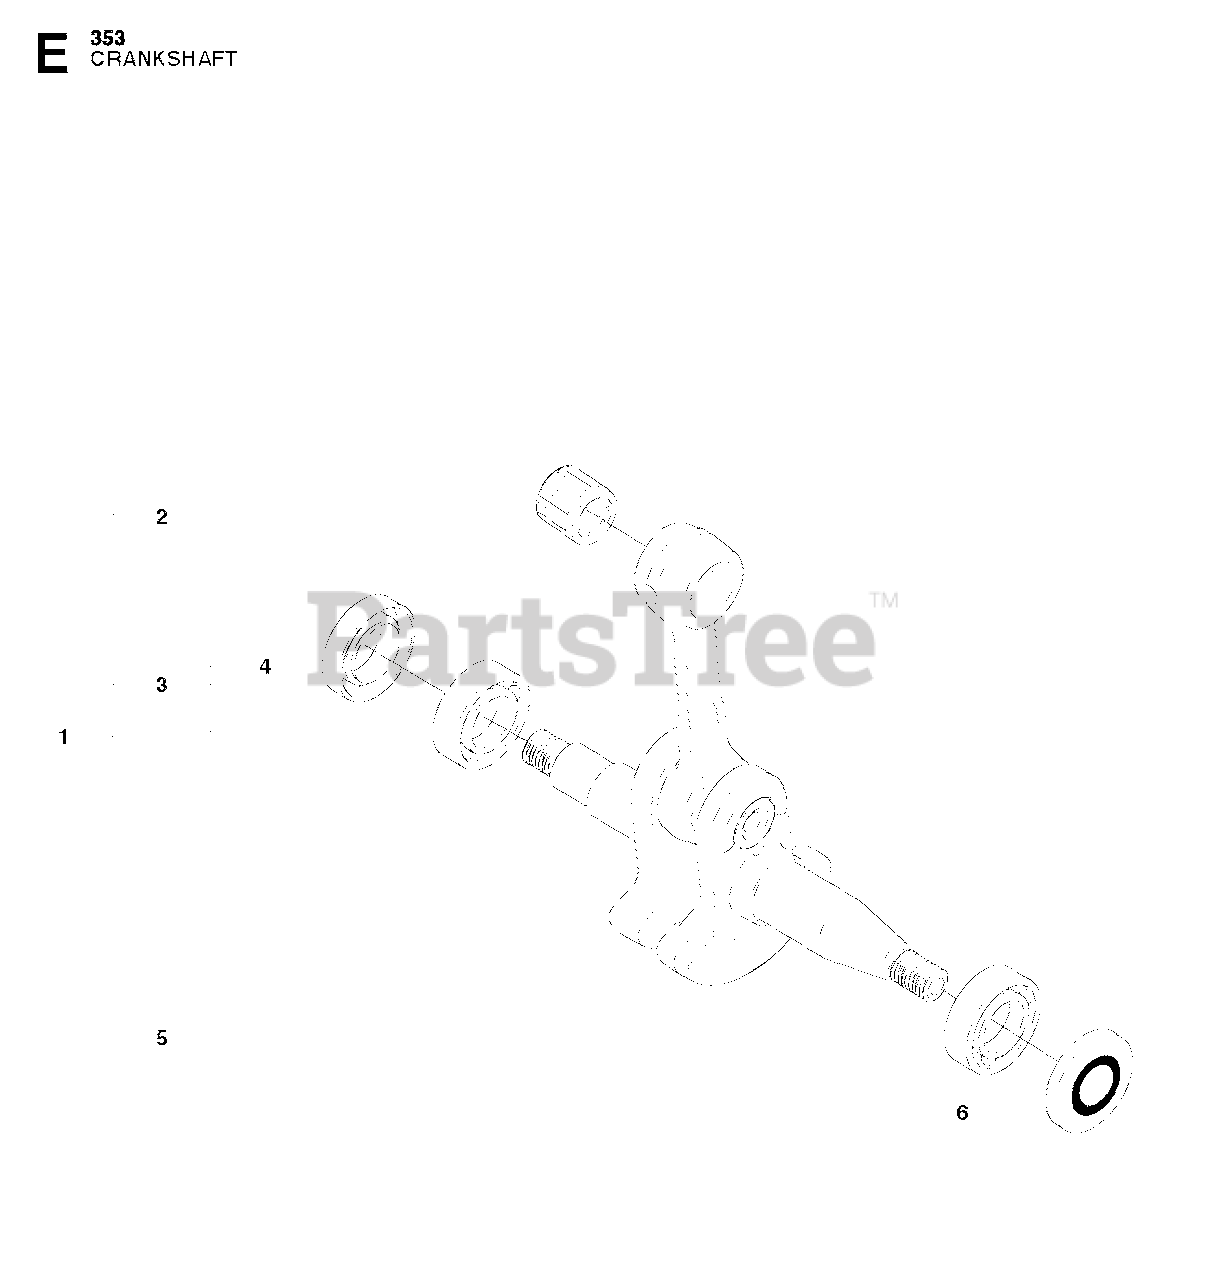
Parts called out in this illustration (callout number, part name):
1	CRANKSHAFT
2	SUPPORT BUSHING
3	BALL BEARING
4	RADIAL SEAL
5	BALL BEARING-6202-C3 SKF
